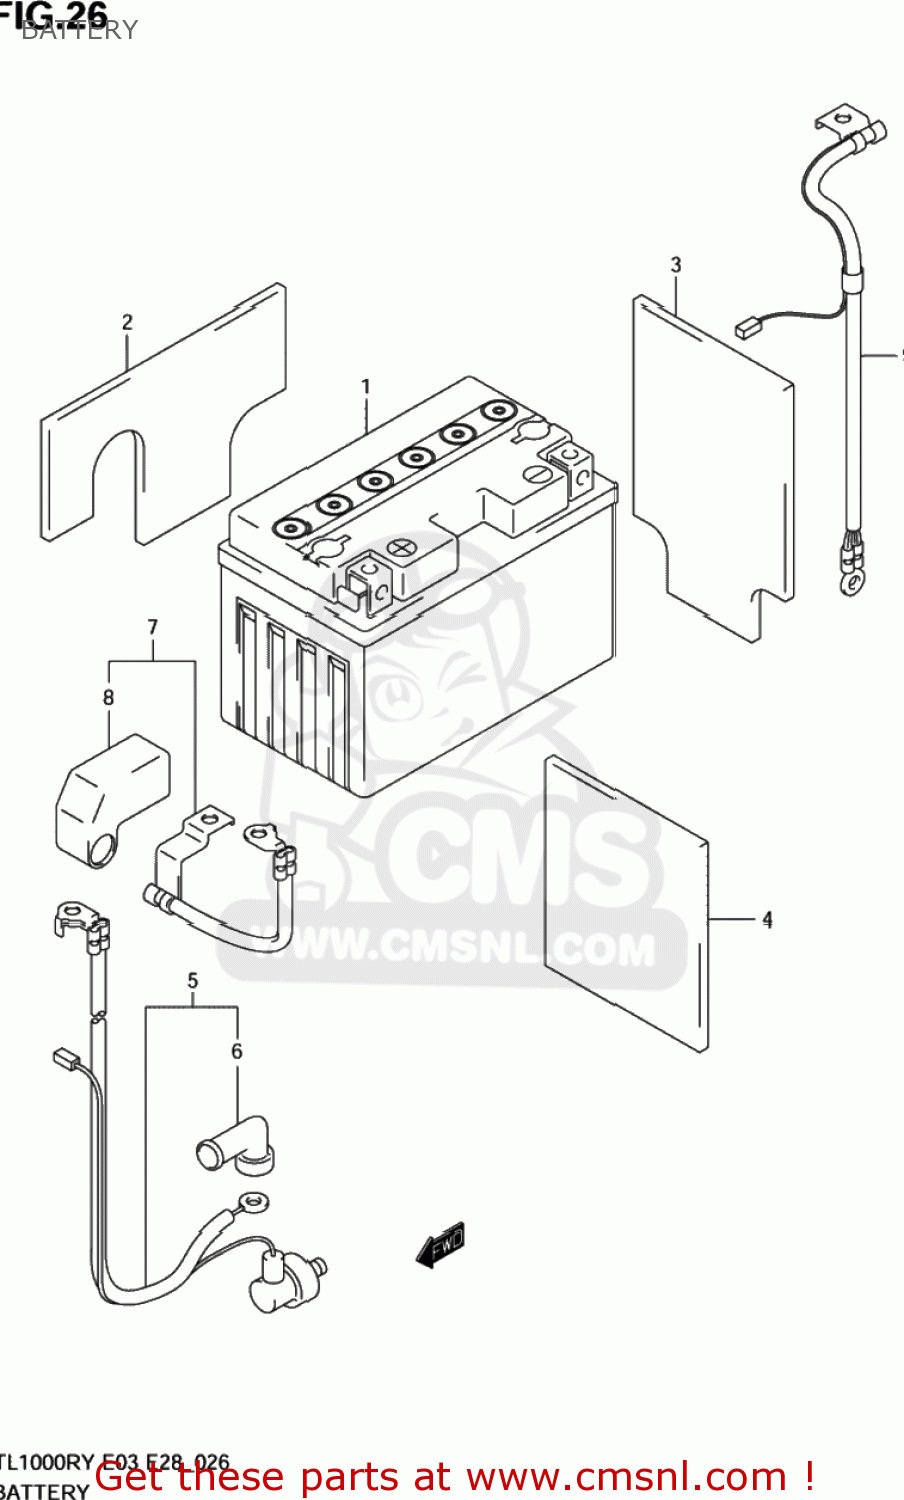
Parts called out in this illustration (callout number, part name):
1	BATTERY ASSEMBLY (12V) YT1
2	PROTECTOR(90X140X8)
3	PROTECTOR(90X140X8)
4	PROTECTOR
5	WIRE,STARTER MOTOR LEAD
6	CAP,STARTER MOTOR LEAD
7	WIRE,BATTERY PLUS
8	CAP,BATTERY PLUS
9	WIRE,BATTERY MINUS
